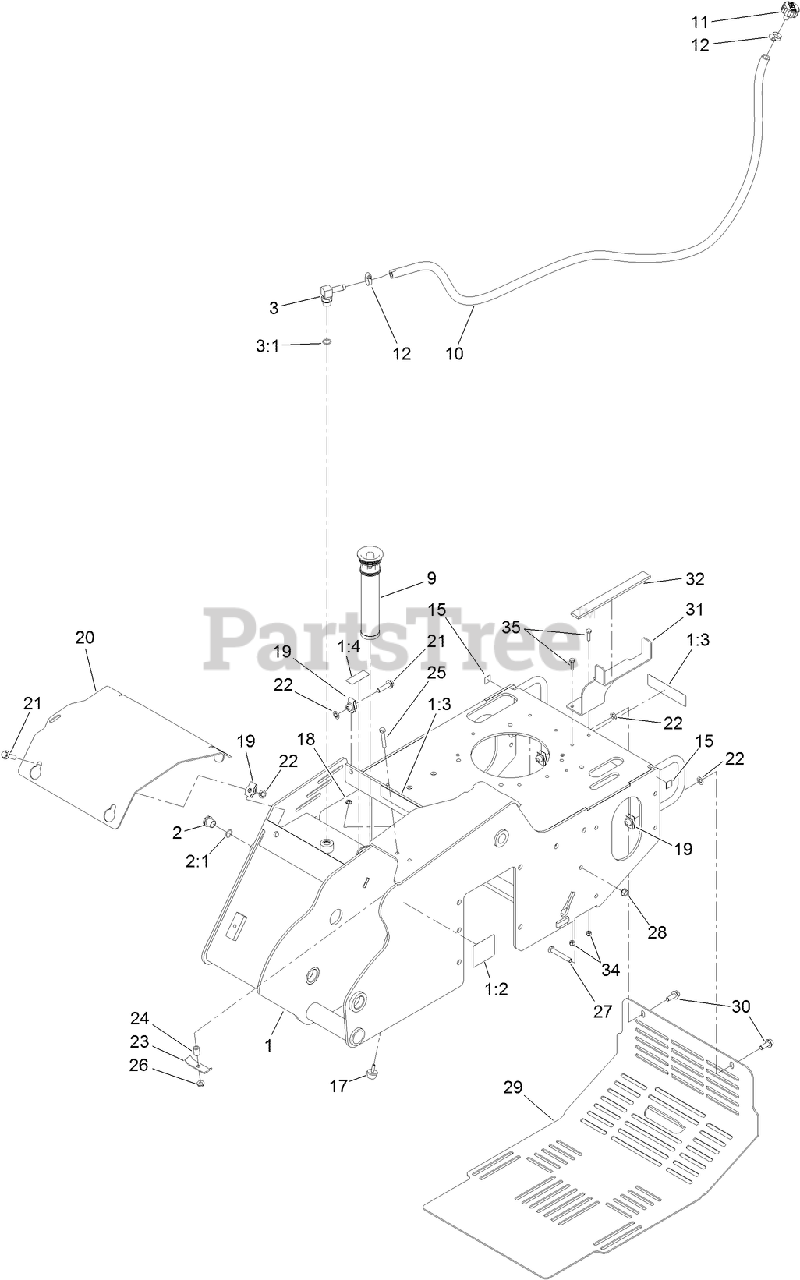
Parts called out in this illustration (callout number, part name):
1	MAIN FRAME ASM
1:2	DECAL-WARNING
1:3	DECAL-DANGER
1:4	DECAL-OIL, HYD
2	SIGHT GLASS ASM
2:1	O-RING
3	FITTING-ELB 90
3:1	O-RING
9	IN-TANK FILTER ASM
10	HOSE-BREATHER
11	BREATHER
12	CLAMP-HOSE
15	DECAL-POINT, LIFT
17	BUMPER
18	NUT-HF
19	Nut-Tinnerman
20	PLATE-COVER, FRONT
21	SCREW-HHF
22	NUT-PUSH
23	BRACKET-CLAMP
24	SPACER
25	SCREW-HH
26	NUT-HF
27	SCREW-HH
28	NUT-FLANGE
29	COVER-REAR
30	SCREW-HHF
31	BRACKET-FUEL TANK
32	PAD-FOAM
34	NUT-LOCK, NI
35	SCREW-HH
